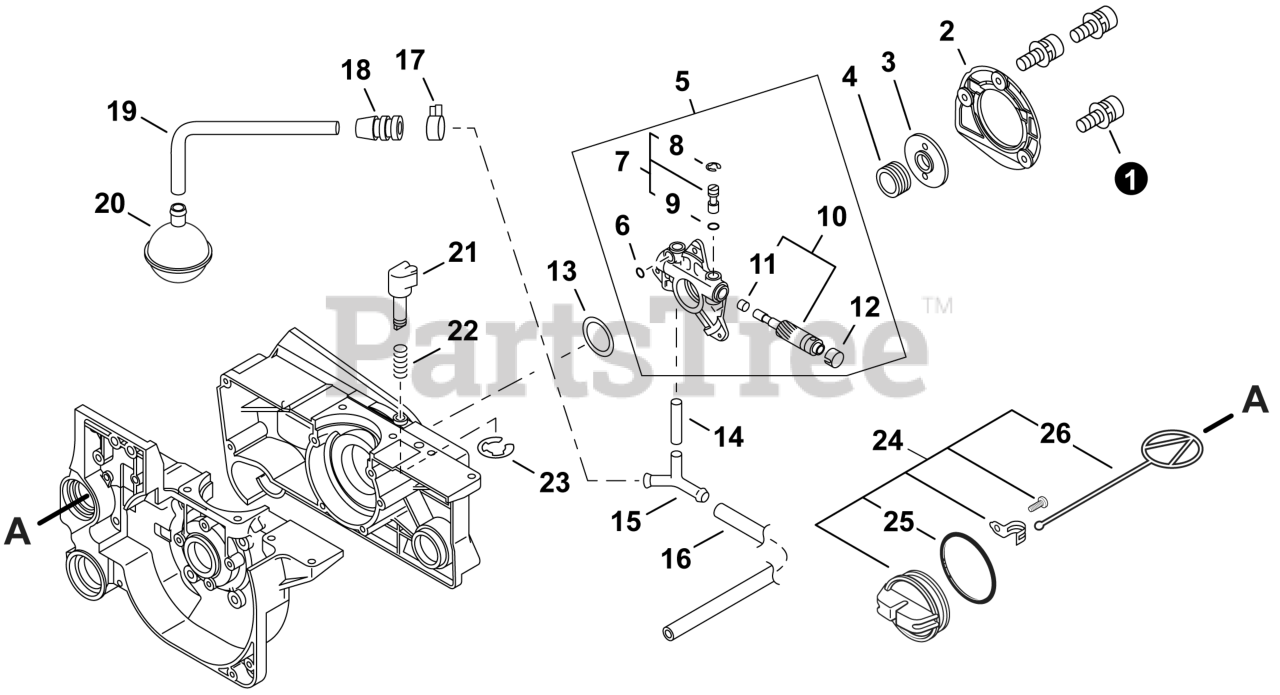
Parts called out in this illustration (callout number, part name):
1	BOLT 4×12
2	COVER, OIL PUMP - ORANGE
3	WASHER 12
4	GEAR, WORM
5	AUTO-OILER ASSY
6	O-RING 3
7	PIN ASSY, CONTROL
10	PLUNGER KIT
12	CAP, PLUNGER
14	PIPE, OIL 3×6×20
15	CONNECTOR, PIPE
16	PIPE, FUEL 3×6×200
17	CLIP Ø6.5 MM
19	PIPE, OIL
20	FILTER, OIL
23	E-RING 3
24	CAP ASSY, OIL
26	CONNECTOR, CAP L= 60 MM
